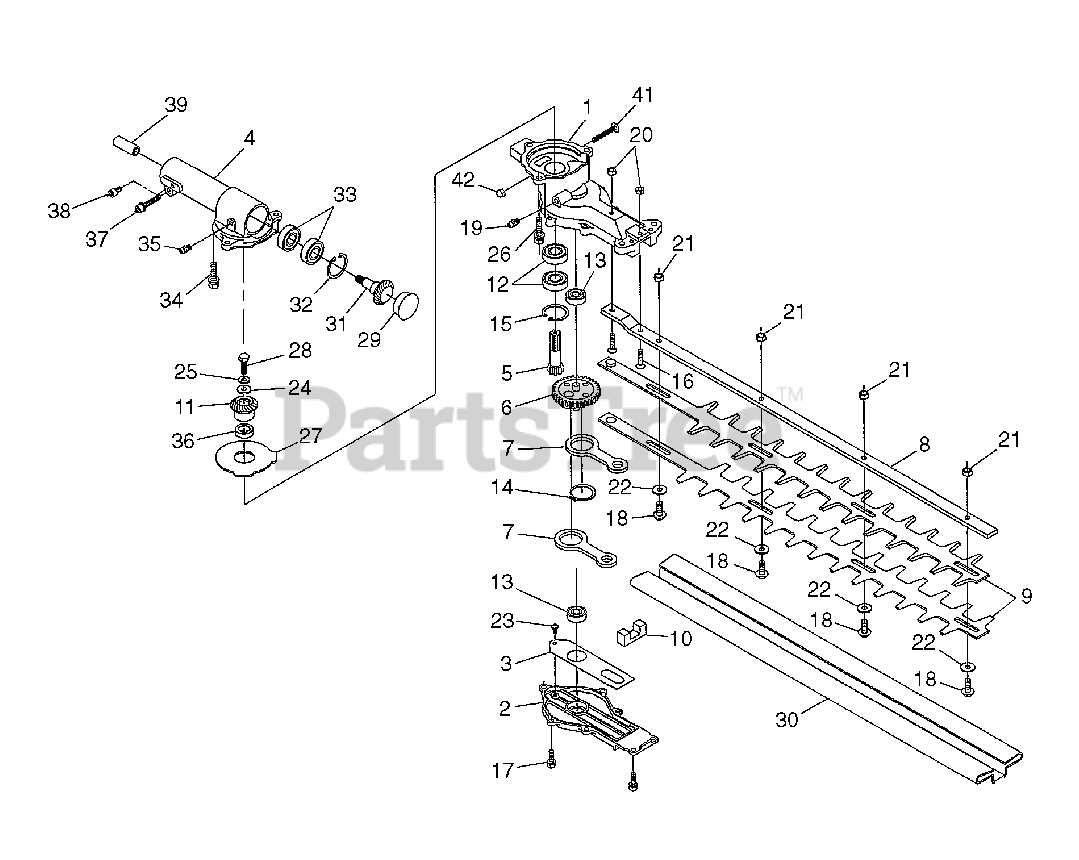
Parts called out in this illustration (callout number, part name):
1	CASING A
4	CASING (REPLS -61A0)
5	PINION GEAR
6	CRANK GEAR
8	GUIDE PLATE
11	BEVEL GEAR A
13	BEARING
14	SNAP RING
17	SCREW
18	SCREW(R3873,388411750&11770
20	U NUT M5
31	BEVEL GEAR B
32	RING,SNAP M26x1.2 RP-318013340
34	BOLT M6X25
38	BOLT, M5 x 12
